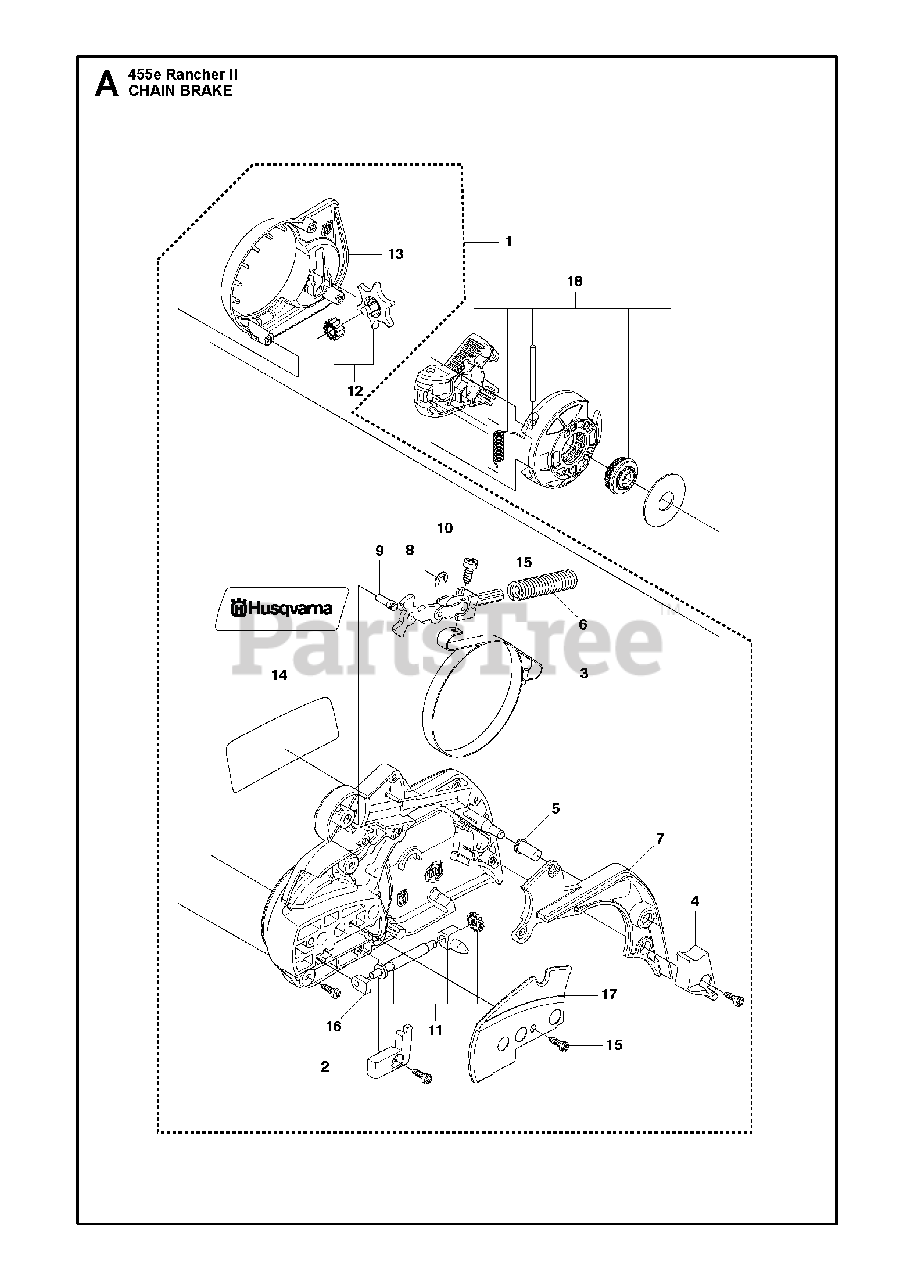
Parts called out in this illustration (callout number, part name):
1	CLUTCH HOUSING COMPLETE
2	COVER
3	BRAKE BAND
4	WEAR GUARD, CHAIN
5	SLEEVE
6	SPRING
7	COVER, CHAIN BRAKE
8	JOINT
9	PIN
10	E-RING 4
11	CHAIN TENSIONER SCREW, COMP.
12	CHAIN TENSIONER WHEEL, COMP.
13	HEAT SHIELD
14	DECAL, CLUTCH HOUSING
15	SCREW
16	BEARING SLEEVE
17	PLATE
18	KNOB, COMPLETE
